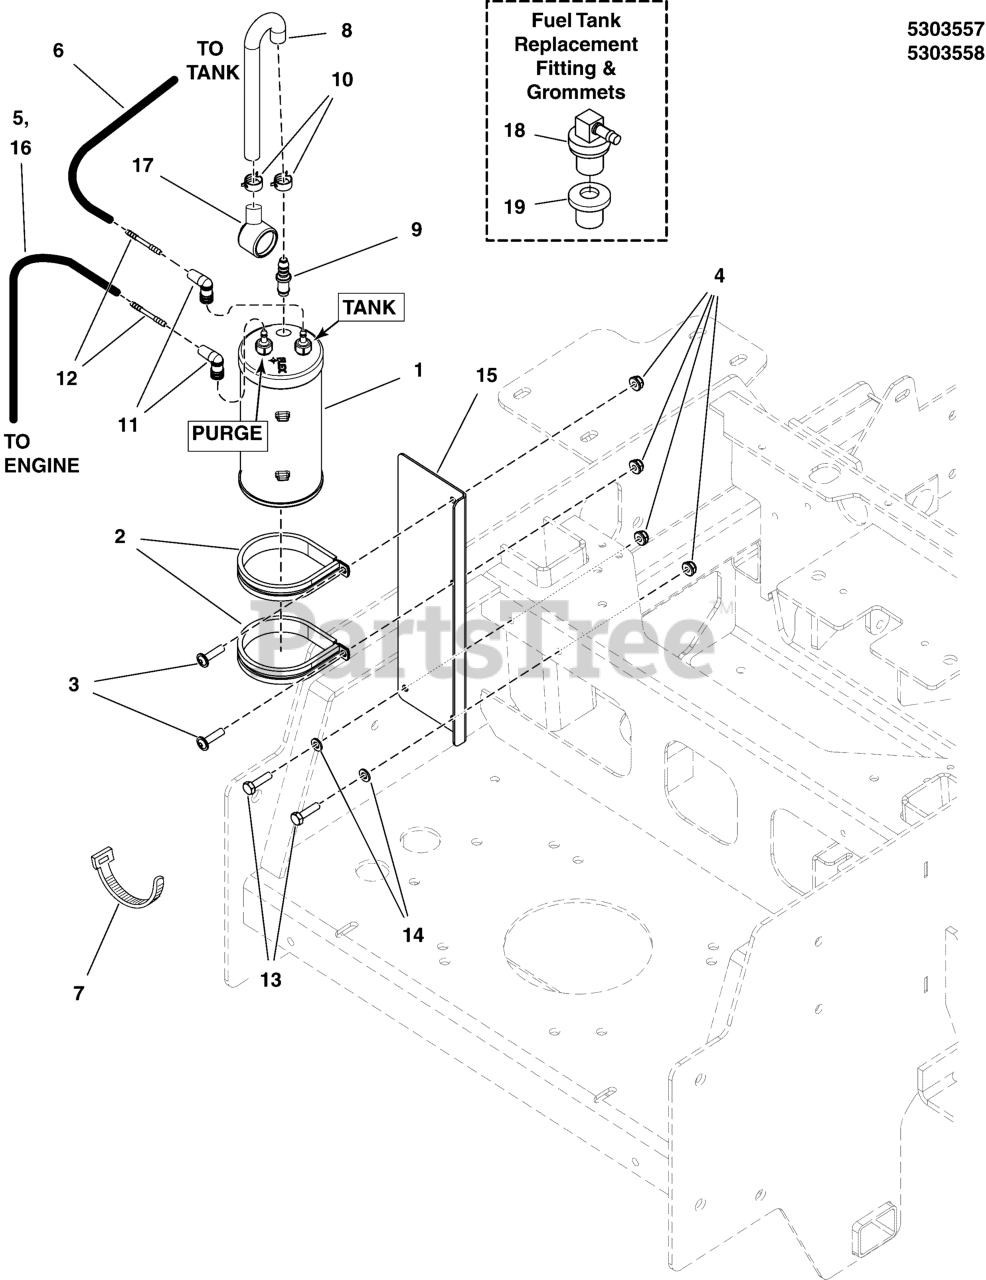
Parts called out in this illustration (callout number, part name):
1	CNSTR, CARB, 6 GAL
2	CLAMP, 3" ID, CUSHIONED, STAINLESS
4	NUT, 1/4-20 Hex Nylock Flange
5	HOSE, VAPOR, 5MM ID, 38.00 LG
7	TIE, SELF-LOCKING, 12"
8	HOSE, FORMED, EVAP CANISTER
9	FITTING, STRAIGHT, 10MMX10MM, PLASTIC
10	CLAMP, Hose
11	FITTING, 90 DEG, 3/16X3/16, SANTOPRENE
12	FITTING, STRAIGHT, 3/16X3/16, PLASTIC
13	BOLT, 1/4-20 X 1" GD5 CZ
14	WASHER, 1/4 SAE
15	MOUNT, EPA CANISTER, S125XT - BLK
16	HOSE, VAPOR, 5MM ID, 27.00 LG
17	DUST FILTER, CANISTER (SV)
18	REMOTE VENT ASSEMBLY
19	GROMMET (SV)
